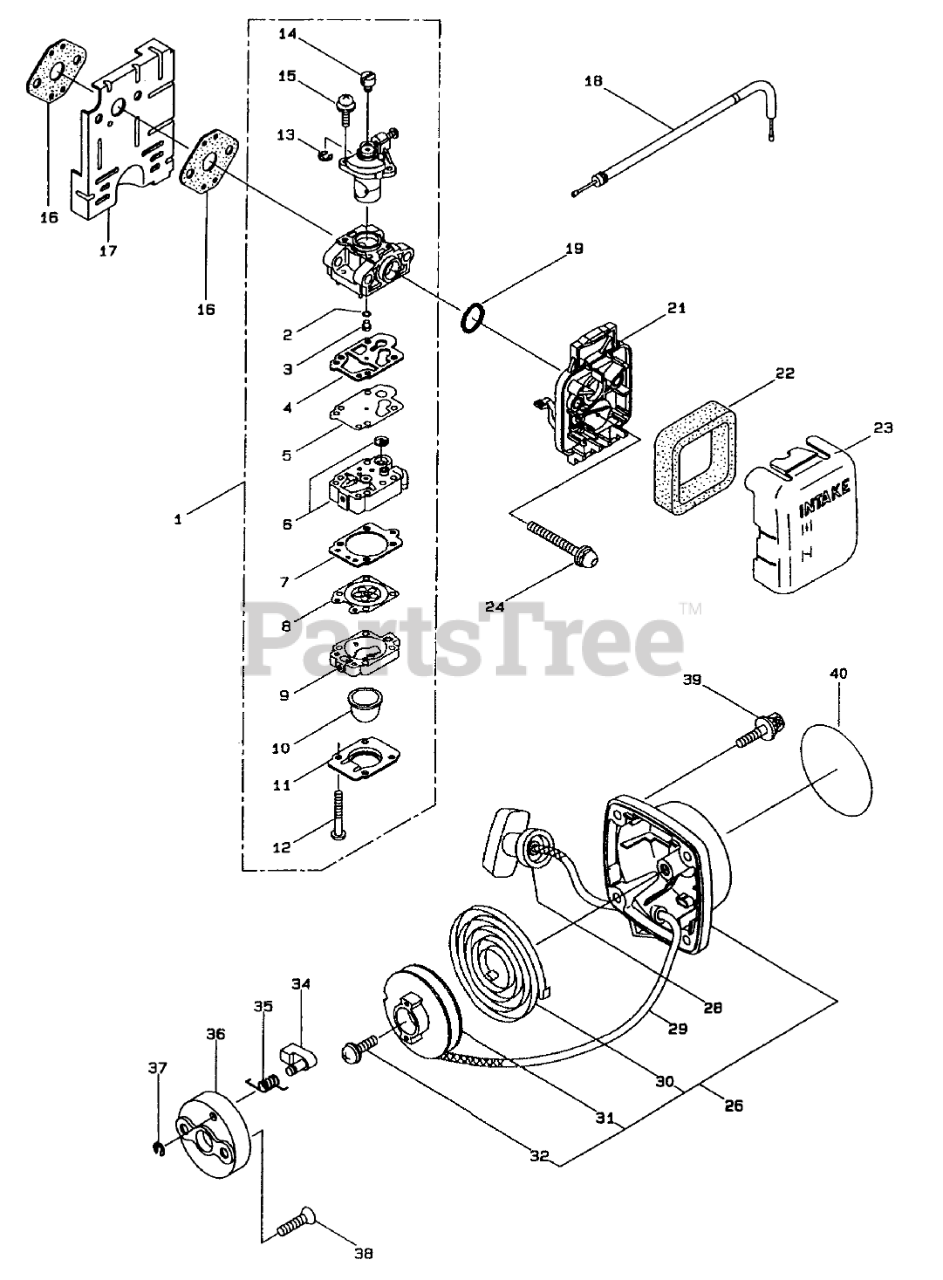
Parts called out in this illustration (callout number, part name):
1	ASM - CARBURETOR
2	O-RING
3	JET - MAIN
4	GASKET (NC)
5	PUMP - DIAPHRAGM (NC)
6	PUMP - BODY (NC)
7	GASKET (NC)
8	ASM - DIAPHRAGM
9	PURGE - BODY (NC)
10	PRIMER
11	PLATE - COVER (NC)
12	SCREW (NC)
13	E-RING
14	SWIVEL
15	SCREW
16	GASKET
17	PLATE - BAFFLE
18	CABLE COMP
19	O-RING
21	HOUSING - AIR CLEANER
22	ELEMENT
23	COVER
24	CAPSCREW
26	Starter Assembly (Incl. Ref. # 27-30)
28	GRIP - STARTER
29	ROPE - STARTER
30	SPRING - SPIRAL
32	SCREW
35	SPRING - RETURN
36	CASE - PAWL
37	RING - SNAP, E-SHAPED
38	SCREW
39	CAPSCREW
40	LABEL - ENGINE
